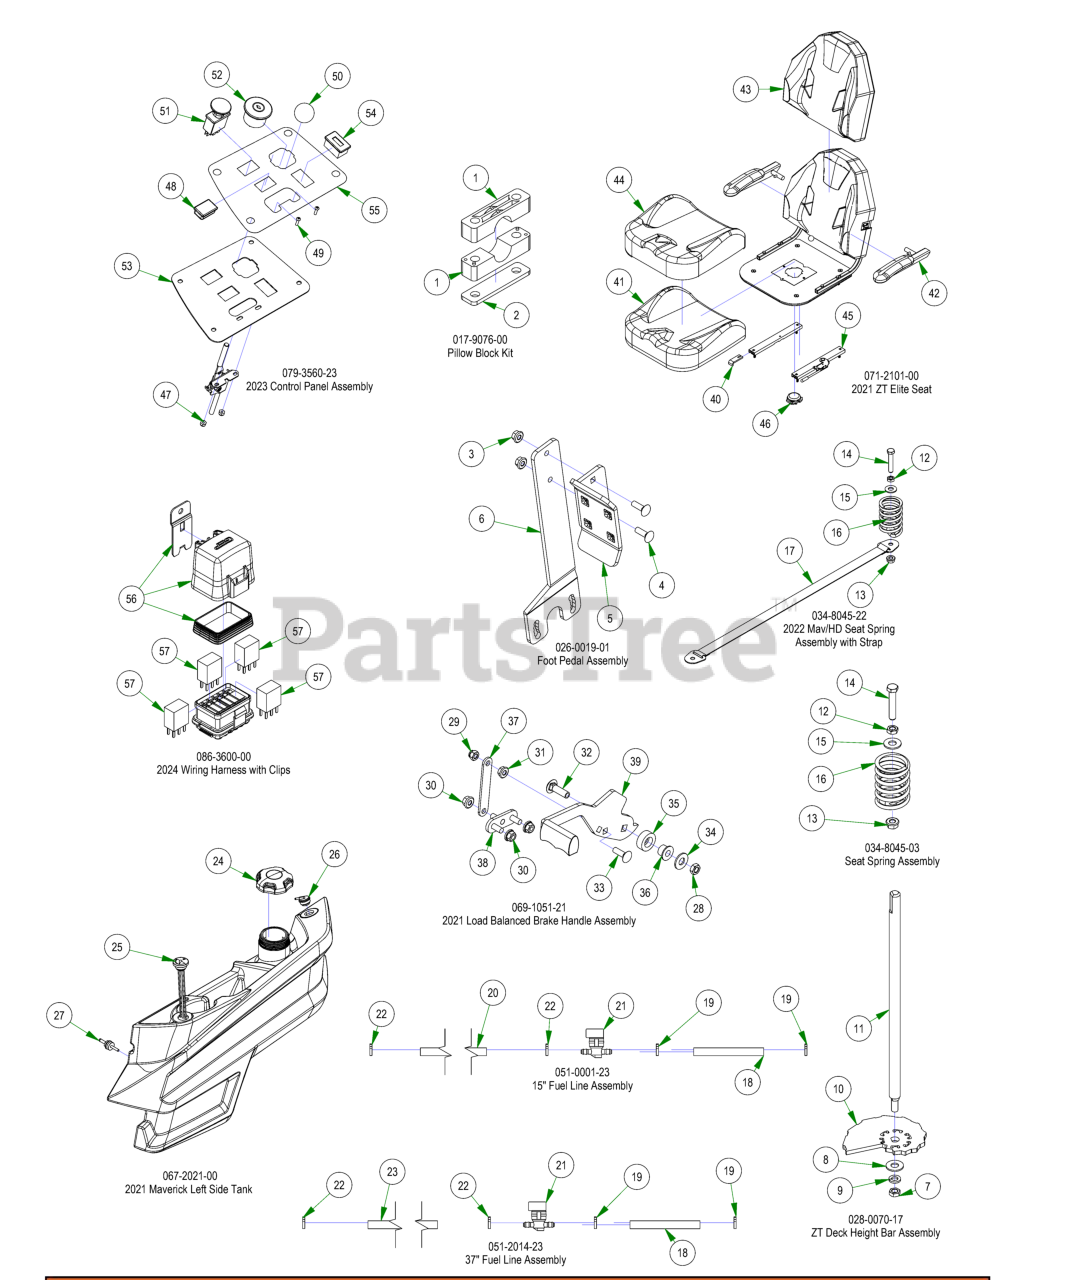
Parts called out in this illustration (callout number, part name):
1	Pillow Block MZ
2	Pillow Block Strap
3	5/16-18 NYLON INSERT FLANGE LOCKNUT ZINC
4	5/16-18 X 1 CARRIAGE BOLT (GR.8) ZINC
5	2017 MZ/ZT Shallow Foot Pedal
6	2017 MZ/ZT Deck Pedal Lever
7	3/8-24 HEX NUT ZINC YELLOW
8	3/8 FLAT WASHER USS (1" OD) ZINC
9	3/8 SPLIT LOCKWASHER ZINC
10	2017 MZ/ZT Cam Plate
11	2017 Deck Height Dial Rod ZT
12	3/8-16 Half Jam Nut
13	3/8-16 HEX SERRATED FLANGE NUT HARD/ZINC
14	3/8-16 X 2 HEX CAP SCREW (GR.5) ZINC
15	3/8 FLAT WASHER USS (1" OD) ZINC
16	Seat Spring
17	Seat Strap with Buckles
18	4" 1/4 Fuel Line
19	1/4 Fuel Hose Clamp
20	11" 1/4 Fuel Line
21	2 Way Fuel Shut-Off Valve
22	1/4 Fuel Hose Clamp
23	37" 1/4 Fuel Line
25	Fuel Gauge w/Grommet
26	Rollover Valve W/Grommet
27	Fuel Pick-up for 067-2021-00
28	3/8-16 HEX JAM 2-WAY REVERSIBLE CENTER LOCKNUT ZINC
29	5/16-18 NYLON INSERT CAP LOCKNUT ZINC (BLK CAP)
30	5/16-18 NYLON INSERT FLANGE LOCKNUT ZINC
31	5/16-18 HEX SERRATED FLANGE NUT HARD/ZINC
32	3/8-16 X 1-1/4 CARRIAGE BOLT ZINC
33	5/16-18 X 1 CARRIAGE BOLT (GR.8) ZINC
34	3/8 FLAT WASHER USS (1" OD) ZINC
35	2015 Brake Lever Spacer
36	.377 ID X .625 OD X .500 HGT X .880 FLNG DIA X .060 FLNG THK
37	Brake Cable Extension Plate
38	Brake Load Balancer Lower Weldment
39	Load Balanced Brake Handle with Grip
40	Black Seat stop from Seat King
41	Seat Cover Molded Foam for 071-2040-18/071-5080-18
42	2017 ZT/Maverick/2020 ZTElite/Avenger Arm Rest Kit
43	Back Cover for 071-2101-00
44	Seat Cover for 071-2101-00/071-2102-00
45	Seat Rails for Outlaw Seat/2020 ZT Elite/ZTAvenger
46	13/14 MZ/Outlaw Seat Switch
47	10-24 Nylon Insert Locknut Zinc Orange Nylon
48	Light Plug
49	10-24 X 5/8 BS Button Head Bolt
50	Throttle Lever Assembly
51	PTO Engager
52	Ignition Switch
53	2022 Maverick HD control panel
54	Tachometer
55	2023 MZ/Magnum/ZT/Maverick Control Panel Decal
56	Relay Block Cover Replacement Kit
